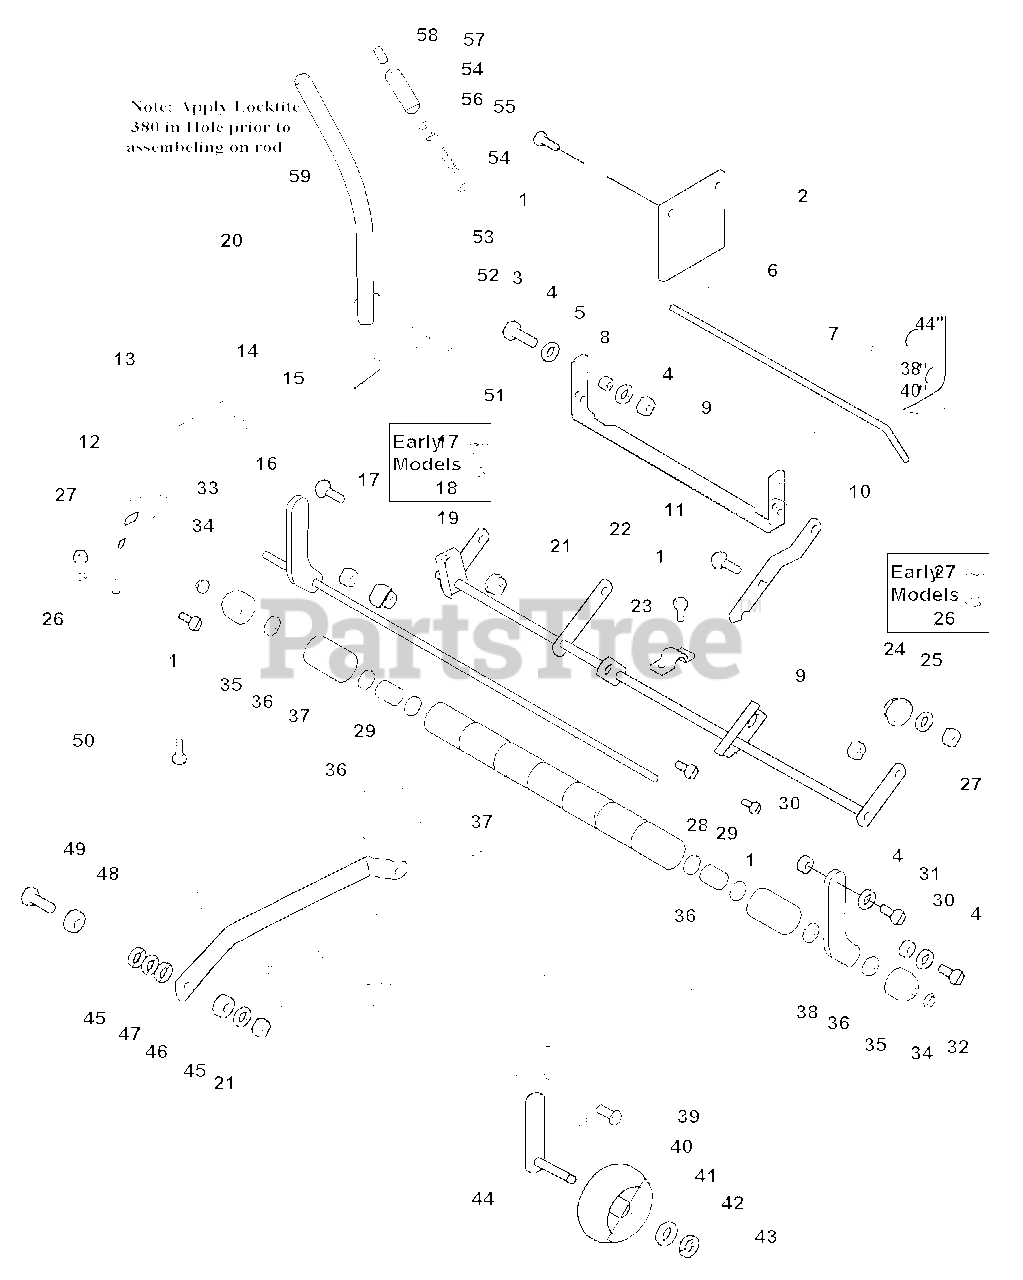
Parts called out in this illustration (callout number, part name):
1	CAPSCREW, Taptite Hex Washer Head, 5/16-18 x 1
2	BRACKET, Upstop
3	CAPSCREW, Hex Head, 5/16-18 x 1-1/4
4	WASHER, 5/16
5	BRACKET, U
6	CLIP, Spring
7	ROD, Transport
9	NUT, Hex Lock, 5/16-18
11	CARRIAGE BOLT, 5/16-18 x 1-1/4
12	QUADRANT 44"
13	DECAL, Height
14	BRACKET, Decal
15	CAPSCREW, Hex Head, Taptite, 5/16-18 x 1/2
16	CARRIAGE BOLT, 3/8-16 x 1
17	NUT, Hex Lock, Alum Insert, 3/8 (Later Models)
17	NUT, Hex, 3/8 (Early Models)
18	WASHER, Lock, 3/8 (Early Models)
19	NUT, Hex Adjusting, .99 DIA .687
21	NUT, Hex Lock, ESNA, 3/8-16
22	ARM ASSEMBLY, Rocker
23	STRAP
25	WASHER, 5/16
26	LOCKWASHER, 5/16 (Early Models)
27	NUT, Hex, Flange Collar Lock, 5/16-18 (Later Models)
27	NUT, Hex, Full, 5/16-18 (Early Models)
28	CARRIAGE BOLT, 3/8-16 x 1-1/2
29	SPACER, 1-1/4 x 5/8
31	CAPSCREW, Hex Head, 5/16-18 x 1
32	CAPSCREW, Taptite Hex Washer Head, 5/16-18 x 1
33	SHAFT ASSEMBLY
34	PUSHNUT, 5/8
35	ROLLER, End
36	WASHER, 5/8
38	BAR, Roller, Support
40	CLIP, Hairpin
41	WHEEL, Gauge
42	WASHER, 1/2
43	E-RING, 1/2
44	ARM ASSEMBLY, Adjustable
45	WASHER, 3/8
47	ARM, Pitch
49	CAPSCREW, Hex Head, 3/8-16 x 2
50	CAPSCREW, Hex Head, 5/16-18 x 3/4
51	NUT, Hex Lock ESNA, 1/4-20
53	CAPSCREW, Hex Head, 1/4-20 x 2-1/4
54	WASHER
55	SPRING, Compression
56	PUSH NUT
57	GRIP, Lift Lever
59	HANDLE ASSEMBLY
